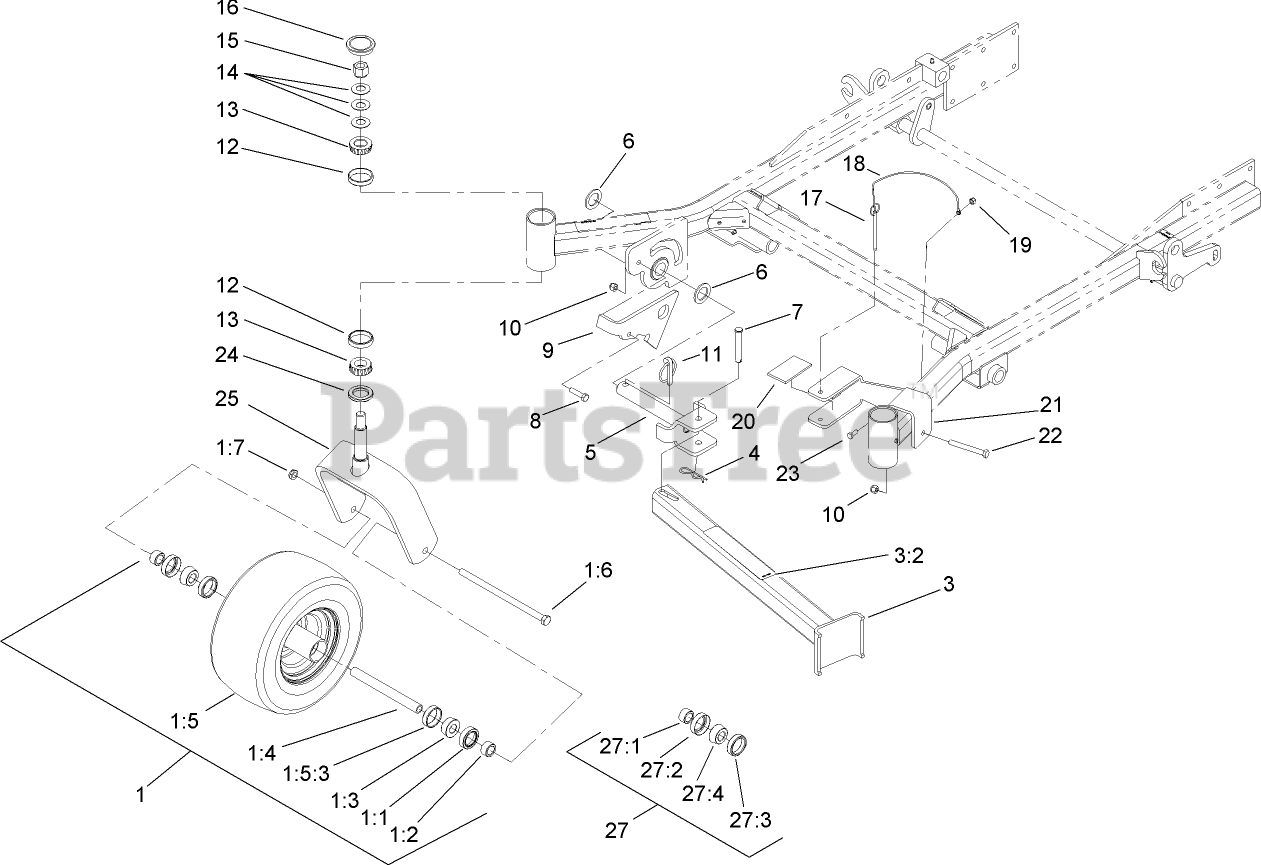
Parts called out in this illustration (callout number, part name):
1	CASTOR WHEEL ASM
1:1	SEAL-BEARING
1:2	SPACER-BEARING
1:3	BEARING-CONE, TAPER
1:4	SPACER-CASTER, FRONT
1:5	WHEEL AND TIRE ASM (SEMI-PNEUMATIC)
1:5:3	BEARING-CUP
1:6	SCREW-HH
1:7	NUT-LOCK, NI
3	Leg ASM
3:2	DECAL-Z STAND
4	PIN-HAIR
5	PIN-PIVOT
6	WASHER-THRUST
7	PIN-CLEVIS
8	SCREW-HH
9	BRACKET-LATCH
10	NUT-LOCK, NI
11	PIN-LYNCH
12	BEARING-CUP, TAPERED
13	BEARING-CONE, TAPERED
14	WASHER-BELLVILLE
15	NUT-LOCK, NI
16	CAP-GREASE
17	PIN-HITCH, COTTERLESS
18	LANYARD-NYLON
19	NUT-LOCK, NI
20	Cushion-Rubber
21	BRACKET-CRADLE
22	SCREW-HH
23	SCREW-HH
24	SEAL-GREASE
25	CASTER-FORK
27	CASTER WHEEL BEARING KIT
27:1	SPACER-BEARING
27:2	SEAL-BEARING
27:3	BEARING-CUP
27:4	BEARING-CONE, TAPER
